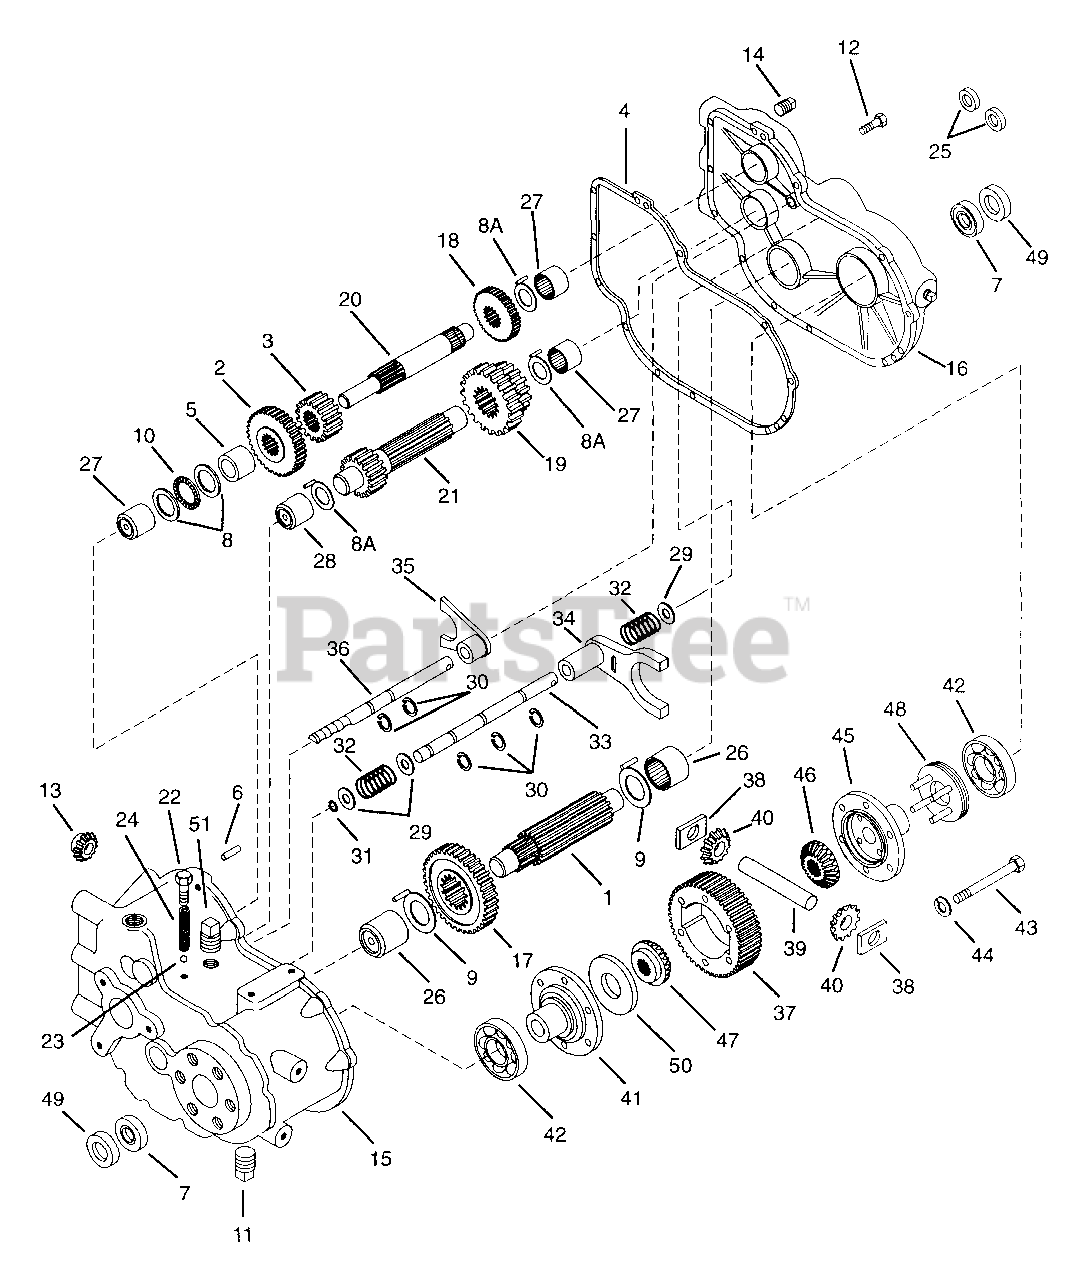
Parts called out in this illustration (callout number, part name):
1	Pinion, Output
2	Gear, Bevel (30 teeth)
3	Gear, Spur (16 teeth)
4	Gasket, Case & Cover
5	Spacer, (1-5/8" O.D. x 1-1/64" I.D. x 55/64" thick)
6	Pin. Dowel
7	Seal, Oil
8	Washer, Thrust (1.542 O.D. x 1.007 I.D. x .060 thick)
8A	Wshr, Thrust (1.687 O.D. x 1.007 I.D. x .0575)
9	Wshr, Thrust (2.187 O.D. x 1.257 I.D. x .0575)
10	Bearing, Thrust
11	Plub, Magnetic Drain, 3/8-18
12	Screw, Hex Hd. Threadforming, 5/16-18 x 1
13	Pinion, Bevel
14	Plub, Pipe, 1/8-27
15	Case Assy., Transaxle
16	Cover, Assy., Transaxle
17	Gear, Output (37 teeth)
18	Gear, Spur (23 teeth)
19	Gear, Cluster (20 & 27 teeth)
20	Shaft, Counter
21	Shaft & Gear Shifter
22	Screw, hex Flanged Hd., 1/4-20 x 5/8
23	Ball, Steel, 3/16"
24	Spring, Shifter Fork
25	Seal, Oil
26	Bearing, Needle
27	Bearing, Needle
28	Bearing, Needle
29	Washer, Thrust (.917 O.D. x .507 I.D. x .060 thick)
30	Ring, Retaining
31	Ring, Retaining
32	Spring, Compression
33	Rod, Shift (Differential Lock)
34	Fork, Shift
35	Fork, Shift
36	Rod, Shift (Hi-Low)
37	Gear, Ring
38	Block, Drive
39	Pin, Drive
40	Pinion, Bevel
41	Carrier, Differential
42	Bearing, Ball
43	Screw, Hex Flanged Hd., 3/8-16 x 2-3/4
44	Lockwasher, 3/8"
45	Carrier, Differential
46	Gear, Bevel
47	Gear, Bevel
48	Collar Assembly, Shift
49	Spacer (2-1/8" O.D. x 1-5/32 I.D. x 3/8" thick)
50	Washer, Thrust
51	Plug, 3/8-18 Sq. Hd. Pipe
